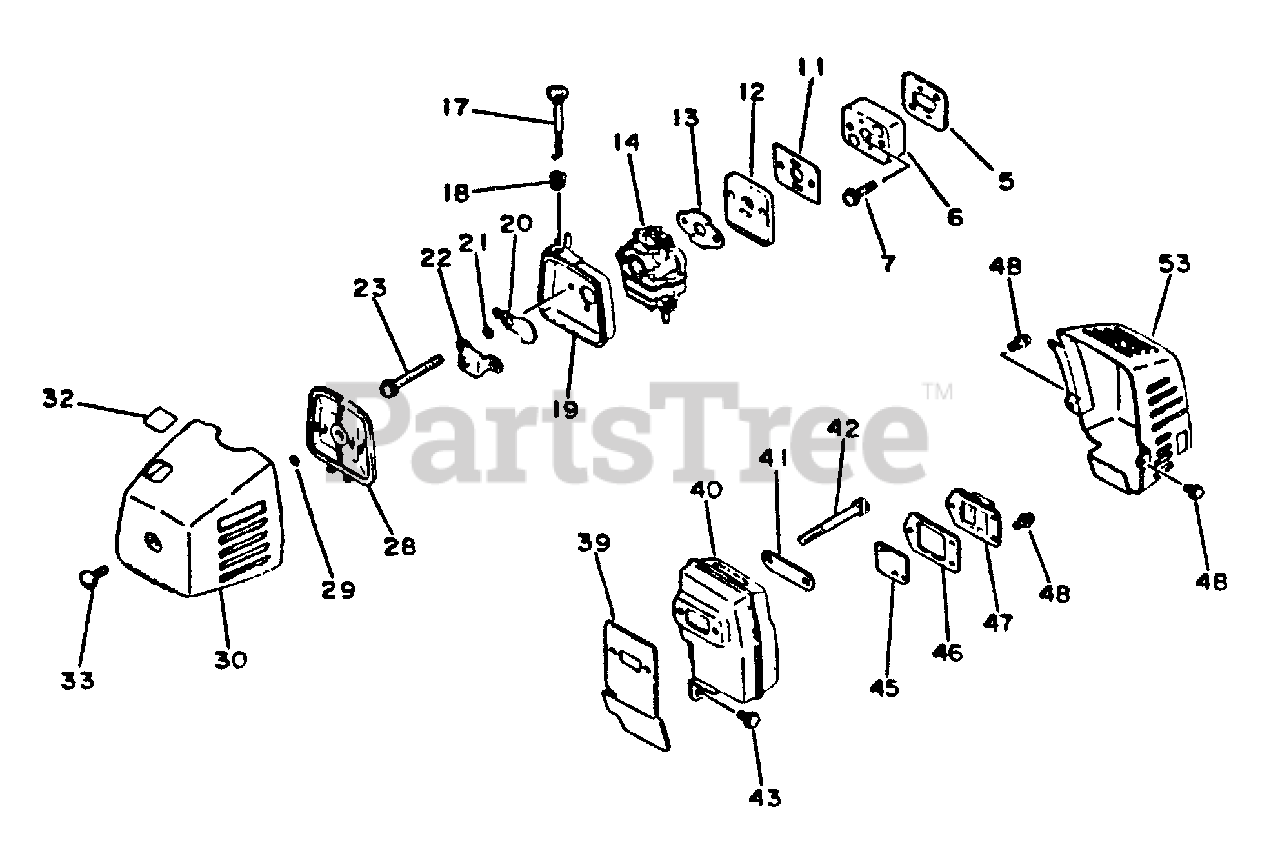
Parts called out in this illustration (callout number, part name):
5	GASKET, INTAKE
6	SCREW 5×22
7	INSULATOR
11	GASKET, INTAKE
12	PLATE
13	GASKET, INTAKE
14	CARBURETOR
17	ROD, CHOKE
18	GROMMET, CHOKE
19	CASE, AIR FILTER
20	SHUTTER, CHOKE
21	WASHER 5.2×8×0.8T
22	PLATE, PREVENT
23	SCREW 5×50
28	FILTER, AIR
30	AIR FILTER COVER ASSY
32	LABEL, CHOKE
39	GASKET, EXHAUST
40	MUFFLER
42	BOLT 5×55
43	SCREW 5×10
45	SCREEN, SPARK ARRESTER
46	GASKET, EXHAUST
47	LID, MUFFLER
48	SCREW 4×8
53	COVER, EXHAUST
